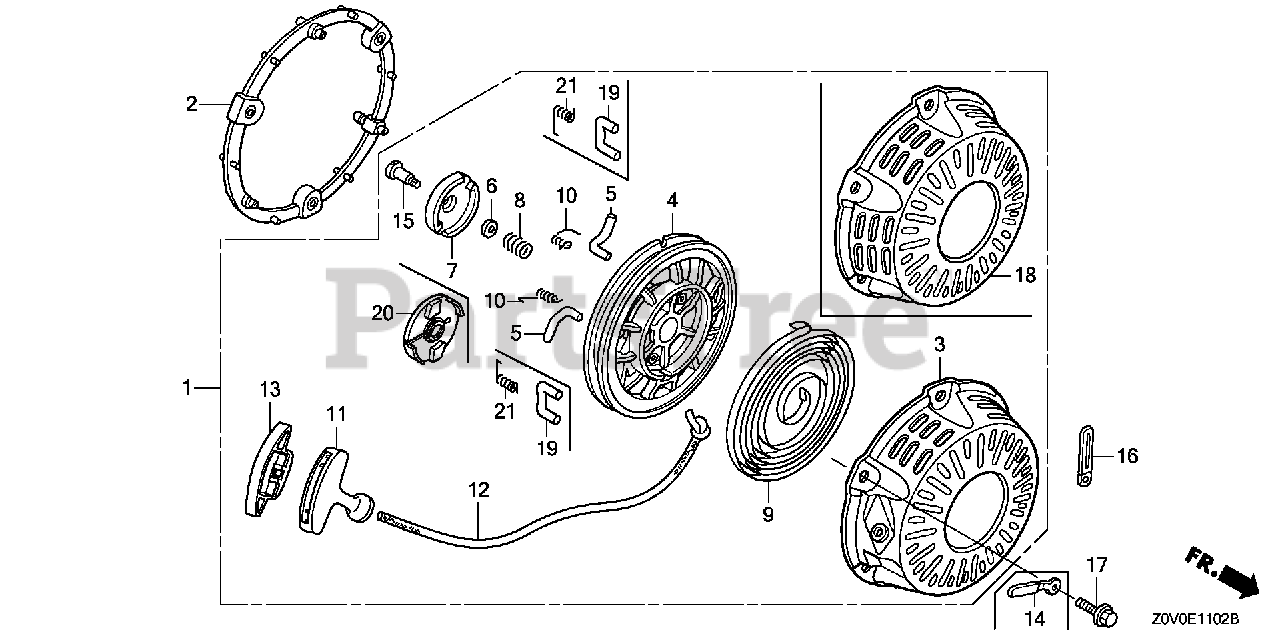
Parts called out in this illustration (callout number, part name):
1	STARTER ASSY., RECOIL *R280* (COO)(FOR U.S.A.) (POWER RED)
1	STARTER ASSY., RECOIL *NH1* (BLACK)
2	SPACER, RECOIL STARTER MOUNTING *NH1* (BLACK)
2	SPACER, RECOIL STARTER MOUNTING *R280* (POWER RED)
3	CASE, RECOIL STARTER *R280* (POWER RED)
3	CASE, RECOIL STARTER *NH1* (BLACK)
4	REEL, RECOIL STARTER (BLACK)
6	PLATE, FRICTION
8	SPRING, FRICTION
9	SPRING, RECOIL STARTER
11	KNOB, RECOIL STARTER
12	ROPE, RECOIL STARTER (#5X55")
13	KNOB, REINFORCEMENT
15	SCREW, SETTING
17	BOLT, FLANGE (6X18)
19	RATCHET, STARTER
20	GUIDE, RATCHET
21	SPRING, RETURN
